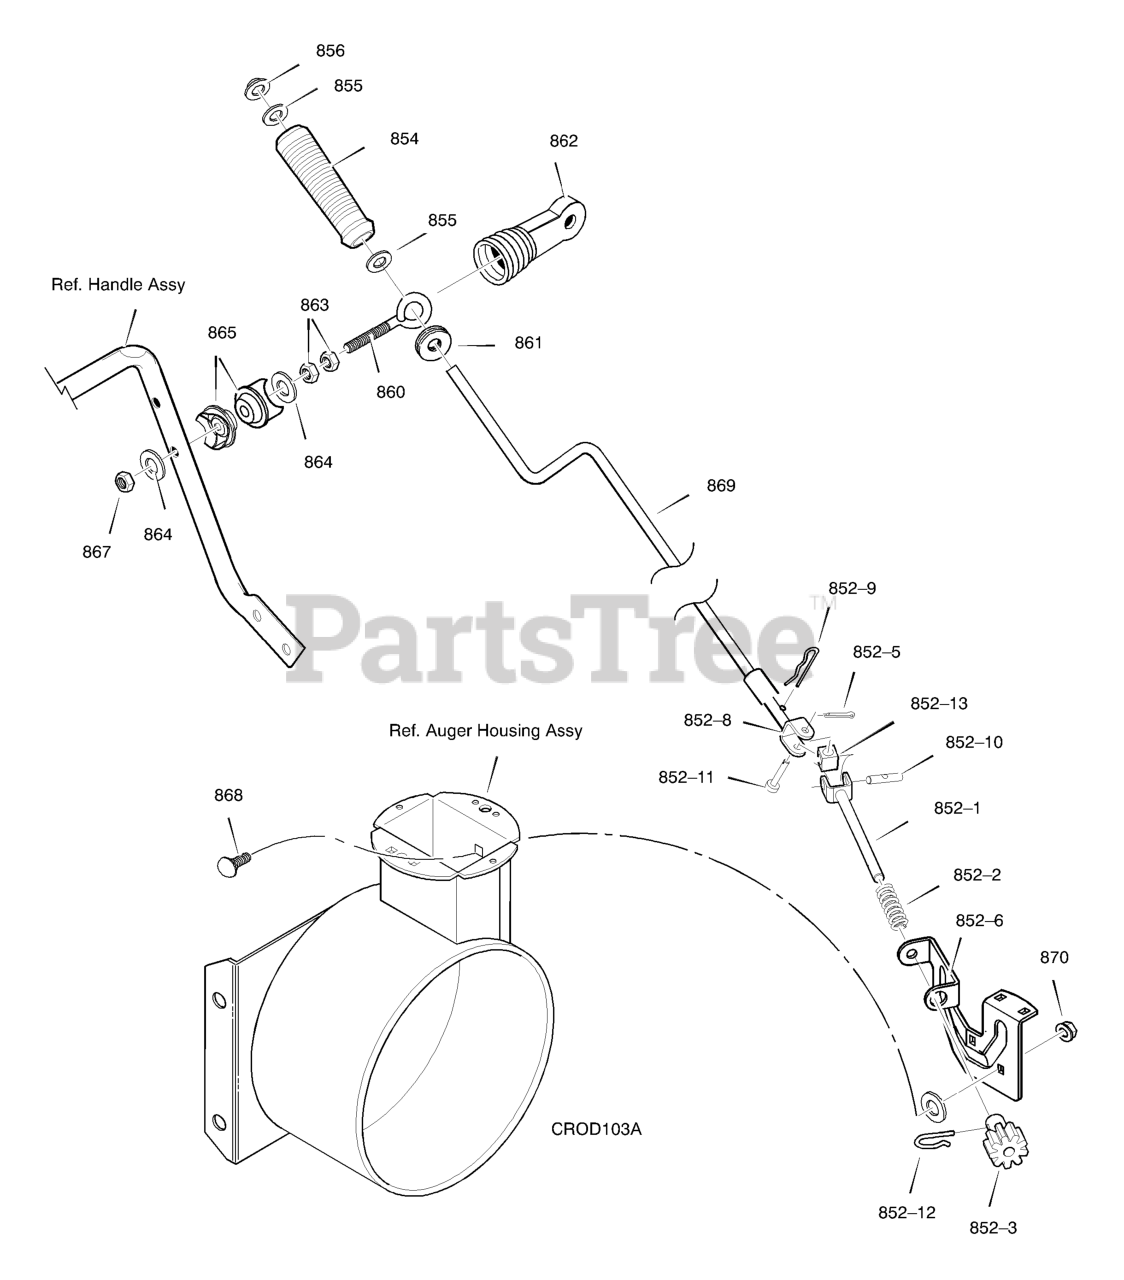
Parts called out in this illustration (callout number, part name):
852-1	ASSEMBLY, YOKE & ROD
852-2	SPRING, COMPRESSION
852-3	GEAR, CHUTE ROTATION 9T
852-5	PIN, COTTER
852-6	BRACKET, GEAR MOUNT
852-7	PIN, COTTER
852-8	ASSEMBLY, YOKE ADAPTER YZ
852-9	PIN, HAIR
852-10	PIN, UNIVERSAL JOINT
852-11	PIN, CLEVIS
852-12	PIN, HAIR
852-13	HOUSING, UNIVERSAL
855	FLATWASHER
856	NUT, PUSH ON 3/8"
860	EYE BOLT 3/8-16X6.50
861	GROMMET, EYE BOLT
862	BOOT, EYE BOLT
863	NUT, 3/8-16 HEXJAM
864	FLATWASHER .406X.81X.066
865	ADAPTER, BOOT (2 REQUIRED)
867	NUT, 3/8-16 HEXNYL
868	BOLT, CARRIAGE 1/4-20 X 1.00
869	CRANK, ASSY CHUTE
870	NUT, 1/4-20 NYLOCK
